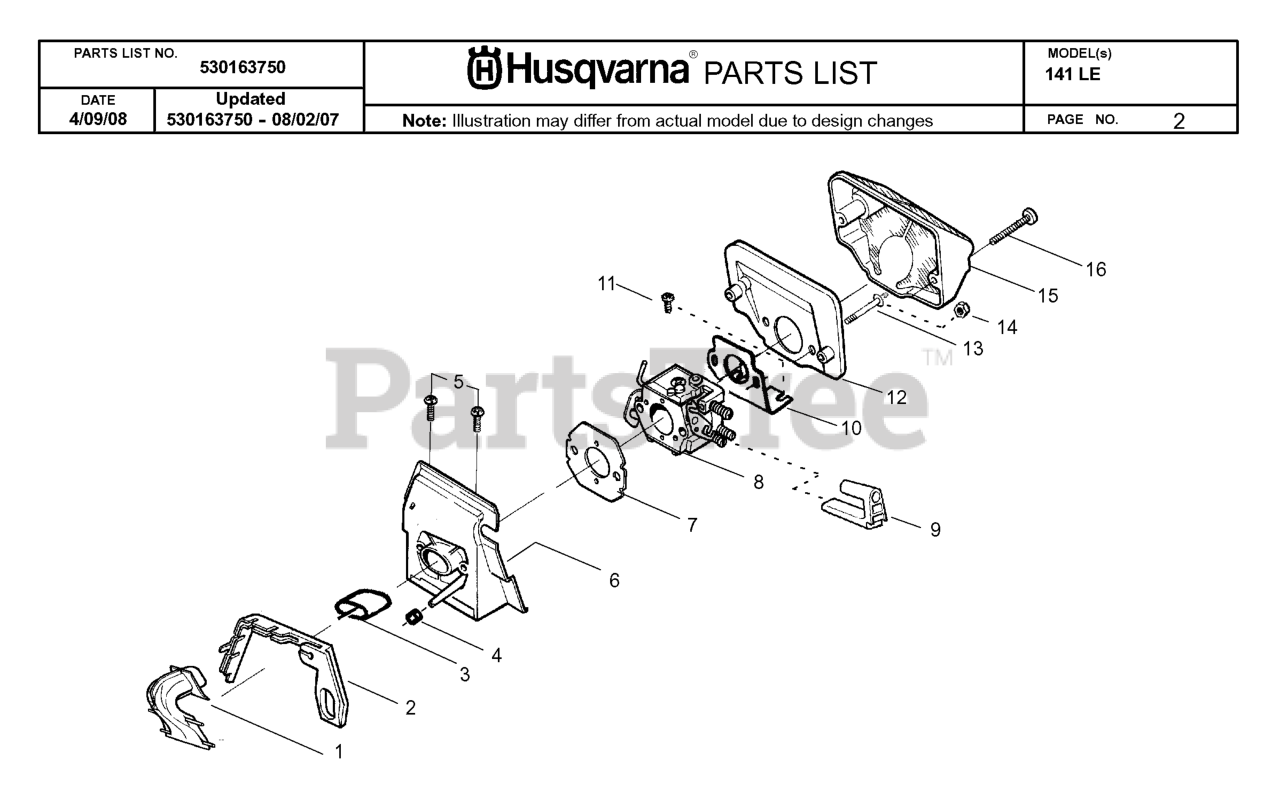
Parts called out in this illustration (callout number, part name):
1	INTAKE HORN
2	TURBO CLEAN SEAL
3	INTAKE PIPE
4	IMPULSE PIPE
6	CARB ADAPTOR
7	GSKT,CARB 36/41
8	CARB WT-660
12	AIR FILTER (BOTTOM)
13	STUD-CARBURETOR
15	AIR FILTER
